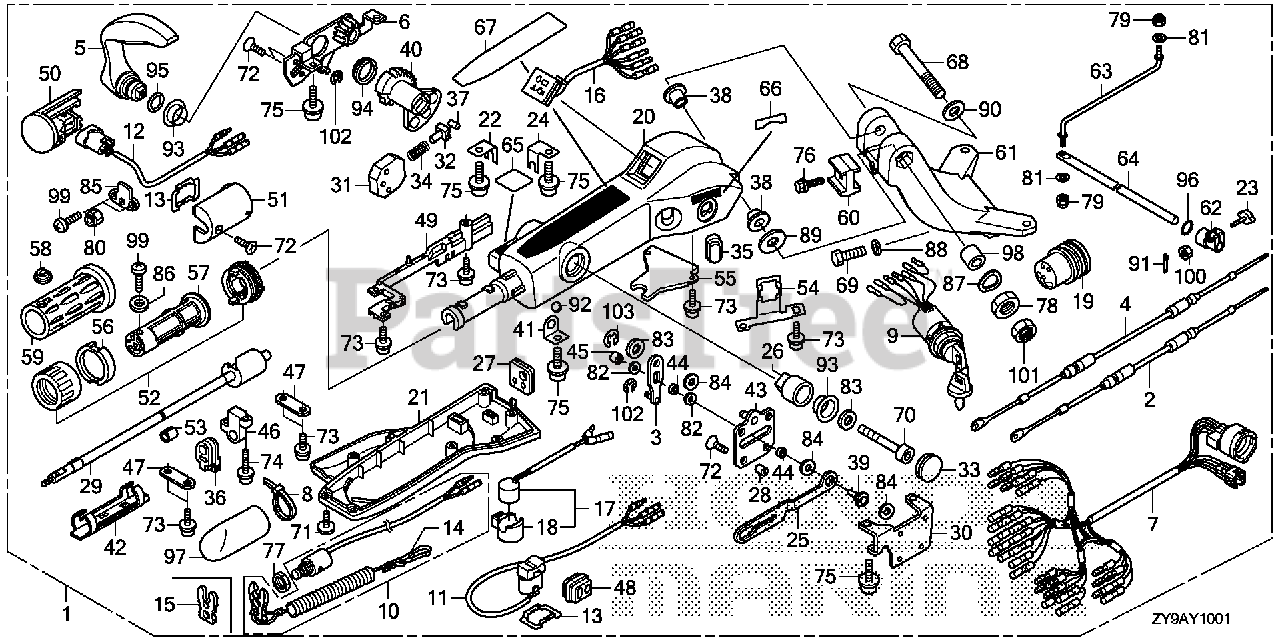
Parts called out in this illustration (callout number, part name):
1	HANDLEBAR KIT *NHB14M* (E) (AQUA MARINE SILVER METALLIC)
1	STRG HNDL KI*NHB14M*
2	CABLE, THROTTLE
3	ARM ASSY., THROTTLE
4	CABLE, SHIFT
5	LEVER, SHIFT
6	FRAME ASSY., SHIFT
7	CABLE ASSY., LONG HANDLE (A)
8	BAND (CONVEX CV-150)
9	SWITCH ASSY., COMBINATION
10	SWITCH ASSY., EMERGENCY STOP
11	SWITCH ASSY., TROLLING CONTROL
12	SWITCH ASSY., POWER TILT
13	PLATE, SWITCH
14	WIRE, EMERGENCY (SINGLE) (DUAL)
15	CLIP, EMERGENCY LOCK
16	LAMP ASSY., INDICATOR
17	BUZZER ASSY., WARNING
18	SUSPENSION, WARNING BUZZER
19	GROMMET, HANDLEBAR CABLE
20	HOUSING *NHB14M* (AQUA MARINE SILVER METALLIC)
21	COVER (LOWER)
22	CLAMP, SHIFT CABLE
23	BOLT, FRICTION
24	CLAMP, THROTTLE CABLE
25	PLATE, LOCK
26	STOPPER, SHIFT
27	GROMMET
28	SPACER
29	SHAFT ASSY., THROTTLE
30	FRAME, THROTTLE
31	GUIDE, SPRING
32	ACTUATOR
33	CAP
34	SPRING
35	GROMMET, POWER TILT SWITCH
36	GROMMET, POWER TILT SWITCH
37	ROLLER
38	BUSH, HANDLEBAR
39	PIN, SLIDE
40	GEAR, SHIFT
41	PLATE, BALL GUIDE
42	GUIDE, THROTTLE HARNESS
43	FRAME ASSY., THROTTLE SUB
44	ROLLER, PLATE
45	ROLLER, CAM
46	STAY
47	PLATE, SHIFT CLAMP
48	GROMMET, SIDE
49	GUIDE, HARNESS
50	BOX ASSY., POWER TILT SWITCH (1)
51	BOX ASSY., POWER TILT SWITCH (2)
52	GRIP ASSY., THROTTLE FRICTION
53	BUSH, THROTTLE SHAFT
54	HOLDER, SWITCH
55	PLATE, HARNESS
56	PAD, THROTTLE FRICTION
57	PIPE, THROTTLE GRIP
58	CAP, GRIP
59	RUBBER, GRIP
60	BLOCK, HEIGHT ADJUSTER
61	BRACKET B, STEERING *NHB14M* (AQUA MARINE SILVER METALLIC)
62	BLOCK, STEERING FRICTION
63	ROD, STEERING FRICTION
64	SHAFT, STEERING FRICTION
65	MARK, EMERGENCY SWITCH INDICATION (EU)
66	MARK, START
67	MARK, HANDLEBAR
68	BOLT, HEX. (12X80)
69	BOLT, HEX. (10X32)
70	BOLT, SOCKET (8X70)
71	BOLT (M5X12)
72	SCREW, FLAT (5X14)
73	BOLT (5X12)
74	BOLT (5X20)
75	BOLT (6X15)
76	BOLT, FLANGE (8X28)
77	NUT, HEX. (16MM) DUAL QTY = (2) (SINGLE)
78	NUT, HEX. (12MM)
79	NUT, SELF-LOCK (8MM)
80	NUT, NYLON (5MM)
81	WASHER, PLAIN (8MM)
82	WASHER
83	WASHER (8MM)
84	WASHER
85	WASHER, PLATE
86	WASHER (5MM)
87	WASHER, WAVE (14MM)
88	WASHER (10MM)
89	WASHER, PLAIN (12MM)
90	WASHER, PLAIN (12MM)
91	PIN, SPLIT (2.0)
92	BALL, STEEL
93	BEARING
94	BEARING
95	O-RING (20.6X1.9)
96	O-RING (15.54X2.26)
97	TUBE, CORD (30MM)
98	COLLAR, DISTANCE (12.2X23X16)
99	SCREW, PAN (5X14)
100	NUT, HEX. (6MM)
101	NUT, HEX. (12MM)
102	E-RING (4MM)
103	E-RING (7MM)
